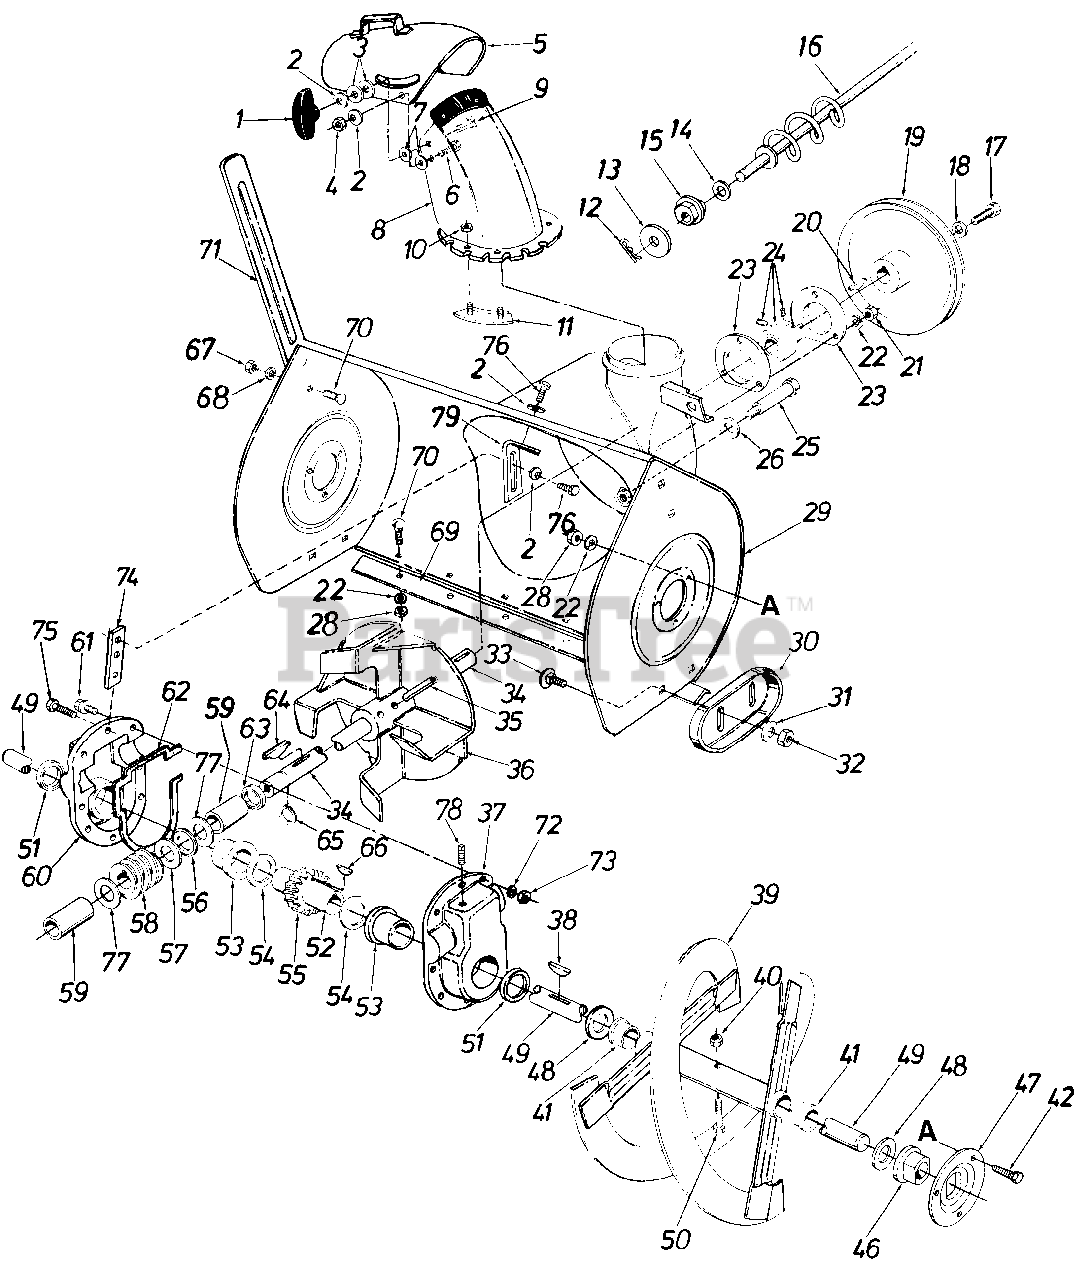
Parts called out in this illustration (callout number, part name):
1	Hand Knob Ass'y.
2	Bell-Wash. .345 I.D. x .88 O.D. x .060
3	Fl. Wash. .312 I.D. x 1.125 O.D. x .125
4	Hex Cent. L-Nut 5/16-18 Thd.
5	Top Chute Ass'y.
6	Carr. Bolt 5/16-18 x .62" Lg.
7	Fl-Wash. .53 I.D. x 1.25 O.D. x .100
8	Chute Ass'y.
9	Carr. Bolt 5/16-18 x 1.00" Lg.
10	Hex Cent. L-Nut 1/2-20 Thd.
11	Chute Flange Keeper Ass'y.
12	Cotter Pin
13	Fl-Wash. .390" I.D. x 1.50" O.D.
14	Fl-Wash. .385" I.D. x .62" O.D.
15	Hex Bushing
16	Chute Crank Ass'y.
17	Hex L-Scr. 5/16-18 x .88" Lg.
18	Bell-Wash. .345 I.D. x .88 O.D. x .060
19	V-Pulley .875 I.D. x 10.12 O.D.
20	#9 Hi-Pro Key 3/16 x 3/4" Dia.
21	Hex Nut 5/16-18 Thd.
22	L-Wash. 5/16" Scr.
23	Bearing Hsg. Self Aligning Brg.
24	Self Aligning Brg. .875 I.D.
25	Stud 3/8-16 x 2.75" Lg.
26	Bell-Wash. .400 I.D. x .88 O.D. x .060
28	Hex Nut 5/16-18 Thd.
29	Blower Hsg. Ass'y.
30	Slide Shoe
31	Bell-Wash. .400 I.D. x .88 O.D. x .060
32	Hex Jam Nut 3/8-16 Thd.
33	Carr. Bolt 3/8-16 x .62" Lg.
34	Blower Axle
35	Spring Pin Spiral 5/16" Dia. x 1.75" Lg.
38	#91 Woodruff Key 1/4" x 3/4" Dia.
40	Hex Ins. L-Nut 5/16-18 Thd.
41	Plastic Bushing
42	Hex Sems Scr. 5/16-18 x .75" Lg.*
46	Flange Brg. w/Flats 1.0" I.D.
47	Bearing Hsg. Spiral Hsg.
48	Fl-Wash. 1.06 I.D. x 1.75" O.D. x .100
49	Spiral Axle 26"
50	Hex Bolt 5/16-18 x 1.75" Lg.
51	Oil Seal 1.50" I.D.
52	Worm Gear Shaft
53	Flange Brg. 1.503 I.D.
54	Fl-Wash. 1.50 I.D. x 2.00 O.D. x .030
55	Double Threaded Worm Gea
56	Thrust Brg. .88 I.D. x 1.44 O.D. x .078
57	Fl-Wash. .88 I.D. x 1.40 O.D. x .1 50
58	Double Threaded Worm L.H.
59	Sleeve Brg. .875 I.D.
60	Complete Gear Hsg. Half R.H.
61	Hex Scr. 5/16-18 x 1.00" Lg.
62	Gasket
63	Oil Seal .875" I.D.
64	#9 Hi-Pro Key 3/16 x 3/4" Dia.
65	Snap Ring for.875" Dia. Shaft
66	#91 Woodruff Key 1/4 x 3/4" Dia.
67	Hex Nut 5/16-18 Thd.
68	L-Wash. 5/16" Scr.
70	Carr. Bolt 5/16-18 x .62" Lg.
71	Drift Cutter
72	Wave Wash. 5/16" Scr.
73	Hex Ins. L-Nut 5/16-18 Thd.
74	Gear Hsg. Support Brk't.
75	Hex Scr. 5/16-18 x 1.25" Lg.
76	Hex Wash. Hd. Self-Tap Scr. 5/16-18 x .75" Lg.
77	Fl-Wash. .88 I.D. x 1.40 O.D. x .1 50
78	Filler Plug
